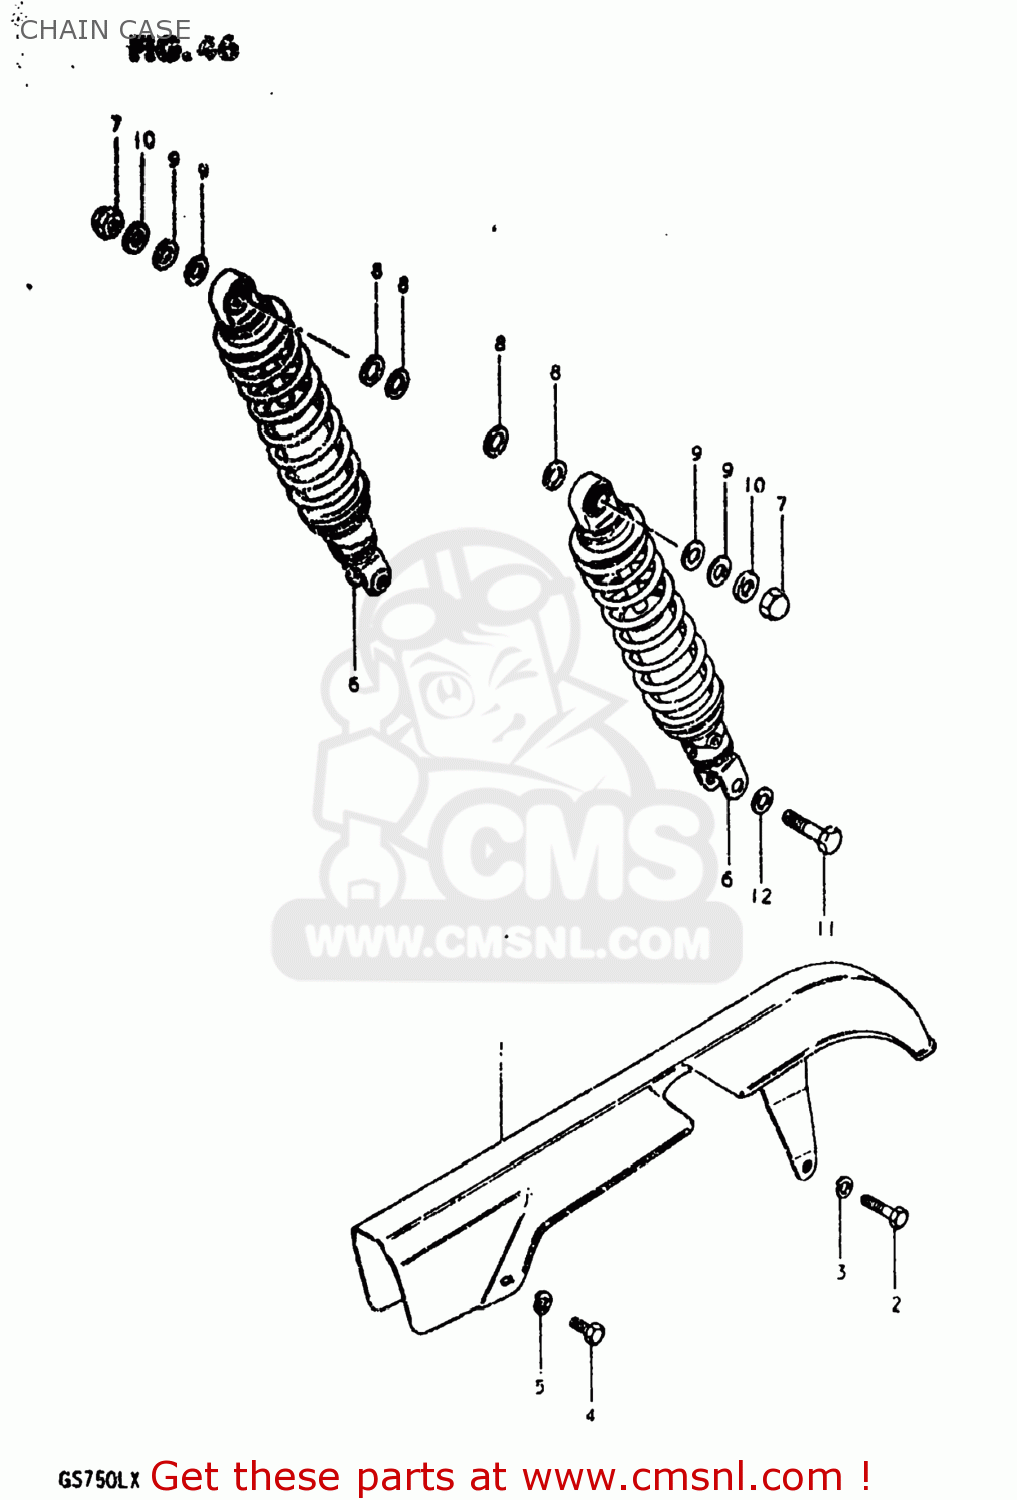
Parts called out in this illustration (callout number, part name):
1	CASE,CHAIN
2	BOLT
3	LOCK WASHER
4	BOLT
5	LOCK WASHER
6	ABSORBER ASSEMBLY,REAR SHOCK
7	NUT, LOWER LH
8	WASHER
9	WASHER
10	WASHER(10.5X24X3.2)
11	BOLT(10X36)
12	WASHER
